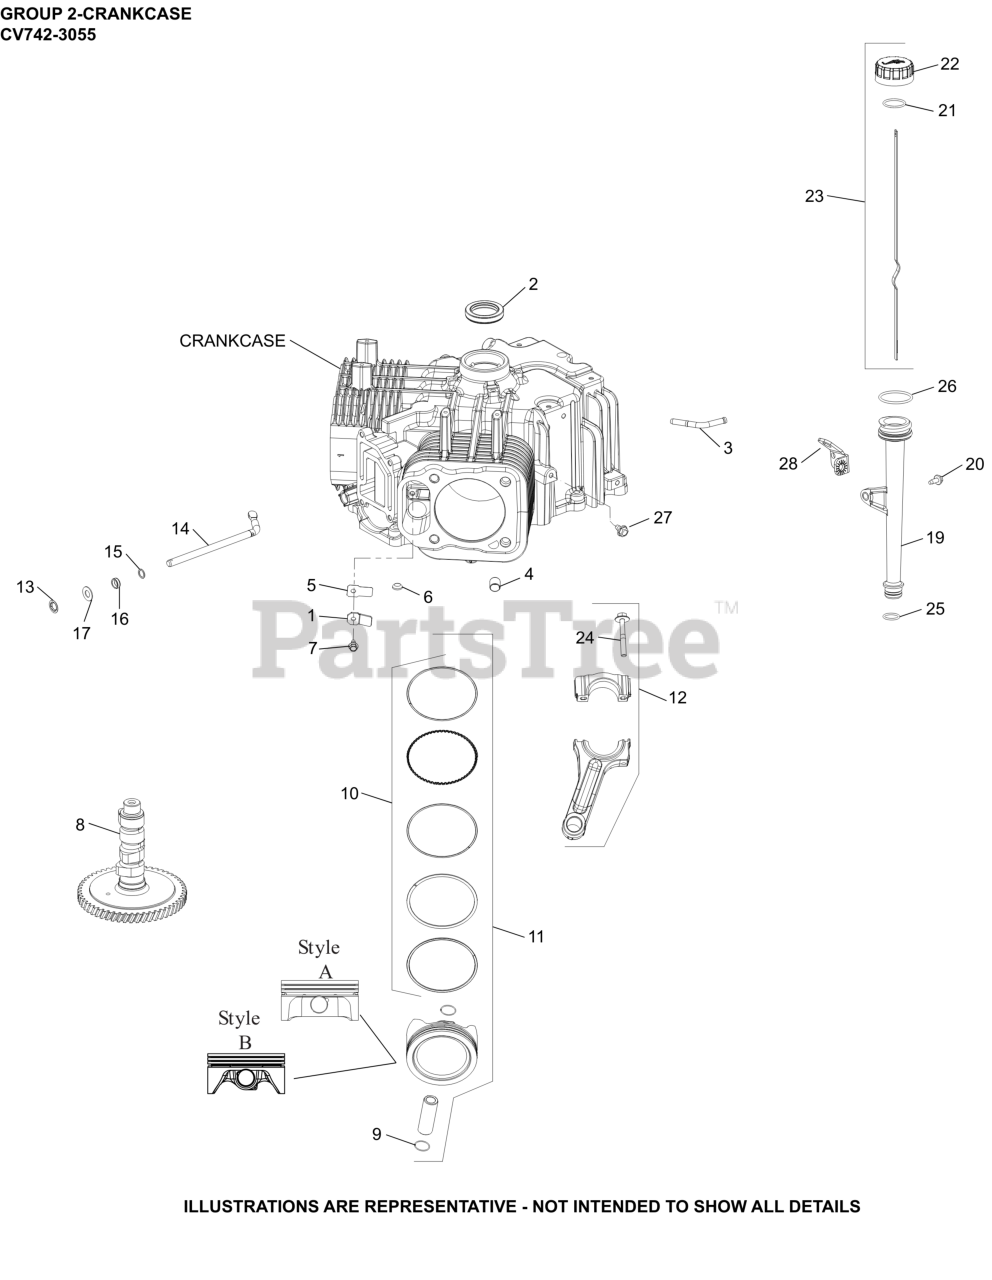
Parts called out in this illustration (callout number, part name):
1	RETAINER, BREATHER REED
2	SEAL, OIL (HELIX LIP)
4	PIN, LOCATING
5	REED, BREATHER
6	PLUG, CUP
7	SCREW, FLG THD FRM M5X.8X10
8	KIT, CAMSHAFT
9	RETAINER, PISTON PIN
10	RING, SET (STD) PINNED
10	RING, SET (.08) PINNED
10	RING, SET (.25) PINNED
10	RING, SET (.50) PINNED
10	RING DISC USE PISTON ASSY PER SPEC
10	RING SET(.08)STYLE A-1.5mm Tp RING THICK
10	RING SET(.50)STYLE A-1.5mm Tp-(#DSC)
11	KIT, PINNED PSTN/RING SET (STD)
11	KIT, PINNED PSTN/RING SET (.08)
11	KIT, PINNED PSTN/RING SET (.25)
11	KIT,PSTN/RING SET (.50)-USE 25 874 20-S
11	KIT,PSTN/RNG STYLE A(STD)
11	KIT,PSTN/RNG STYLE A(.08)
11	KIT,PSTN/RNG STYLE A(.25)USE 2587411-S
11	KIT,PSTN/RNG STYLE A(.50)(#2587404S)
12	ROD, ASSEMBLY CONNECTING
13	RETAINER, RING
14	SHAFT, GOVERNOR CROSS
15	WASHER, FLAT 11/32"
16	SEAL, GOVERNOR CROSS SHAFT
17	WASHER, FLAT 9 MM
19	TUBE ASSEMBLY
20	SCREW, FLG THD FRM M5X0.8X13
21	O-RING, DIPSTICK
22	KIT, OIL FILL CAP (YELLOW)
23	DIPSTICK, ASSY
24	KIT, ROD BOLTS-(#25086677S)
25	O-RING, LOWER OIL FILL TUBE
26	O-RING, UPPER OIL FILL TUBE
27	SCREW, THREAD FORMING
28	BRACKET, OIL FILL TUBE
